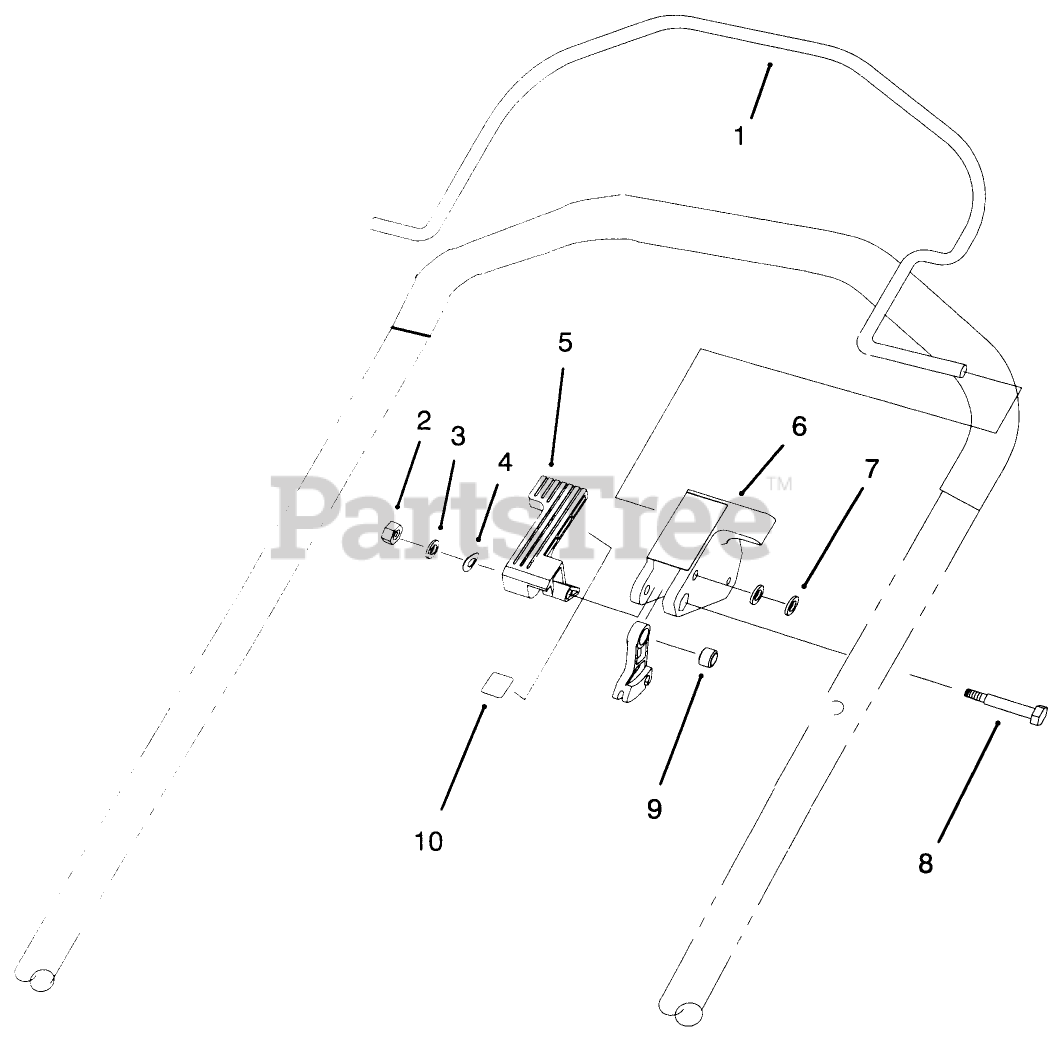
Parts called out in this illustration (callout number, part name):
2	NUT-LOCK, NI
3	WASHER-PLAIN
4	WASHER - SPRING
5	LEVER - SHIFT
6	STOP - PIVOT, PLASTIC
7	WASHER-FLAT
8	SHOULDER BOLT
9	SPACER-LEVER, TRACTION
